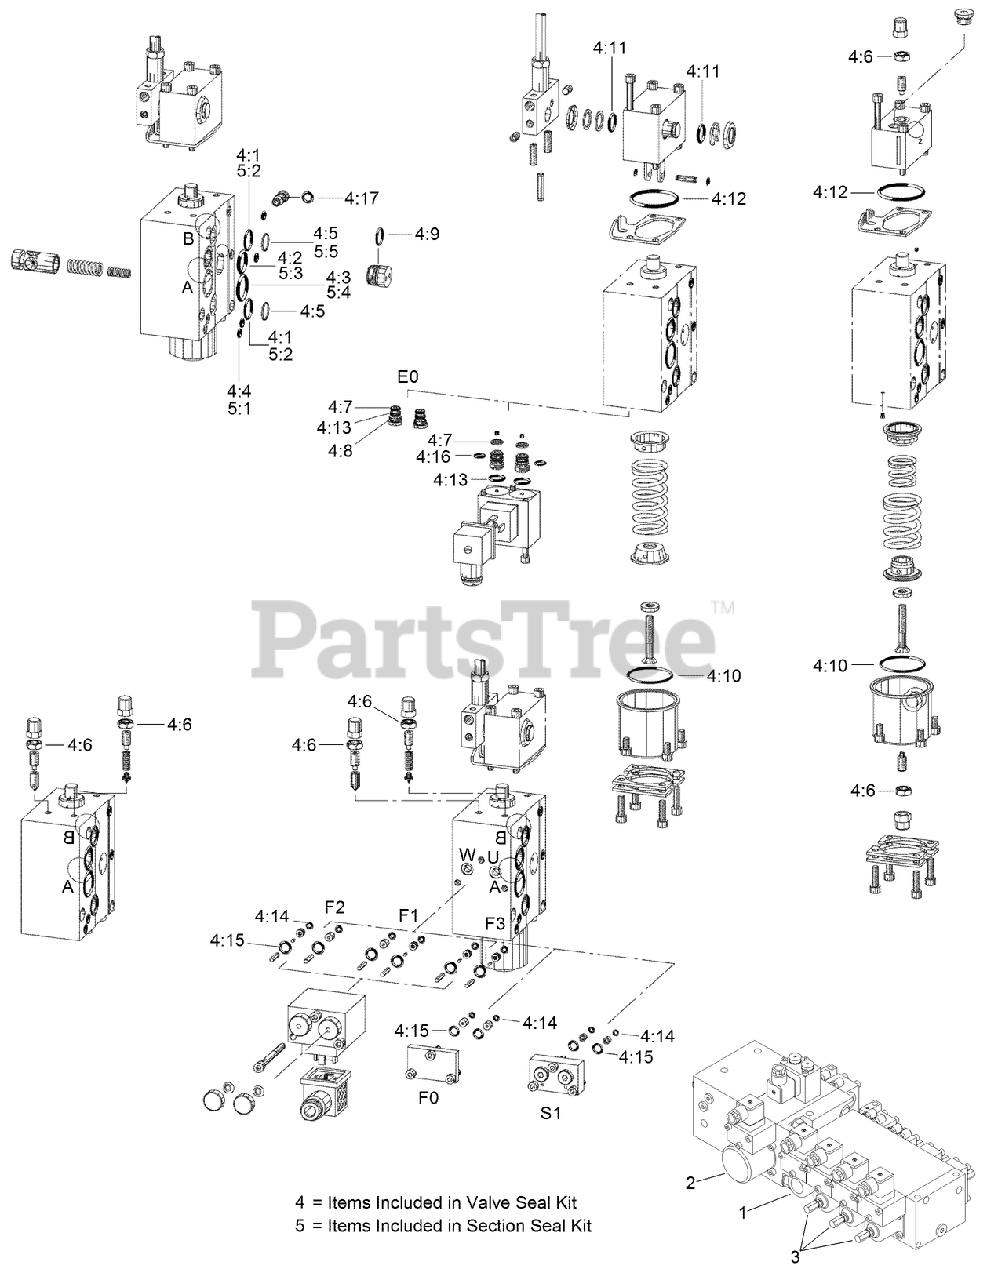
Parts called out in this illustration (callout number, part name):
1	COIL-12V
2	SOLENOID-TWIN, 12V
3	SPOOL-SL
4	VALVE SEAL KIT
4:1	O-RING
4:2	SEAL
4:3	SEAL
4:4	O-RING
4:5	RING-BACKUP
4:6	SEAL-NUT
4:7	Seal-Ring
4:8	O-RING
4:9	O-RING
4:10	O-RING
4:11	O-RING
4:12	O-RING
4:13	O-RING
4:14	O-RING
4:15	O-RING
4:16	O-RING
4:17	O-RING
5	SECTION SEAL KIT
5:1	O-RING
5:2	O-RING
5:3	SEAL
5:4	SEAL
5:5	RING-BACKUP
